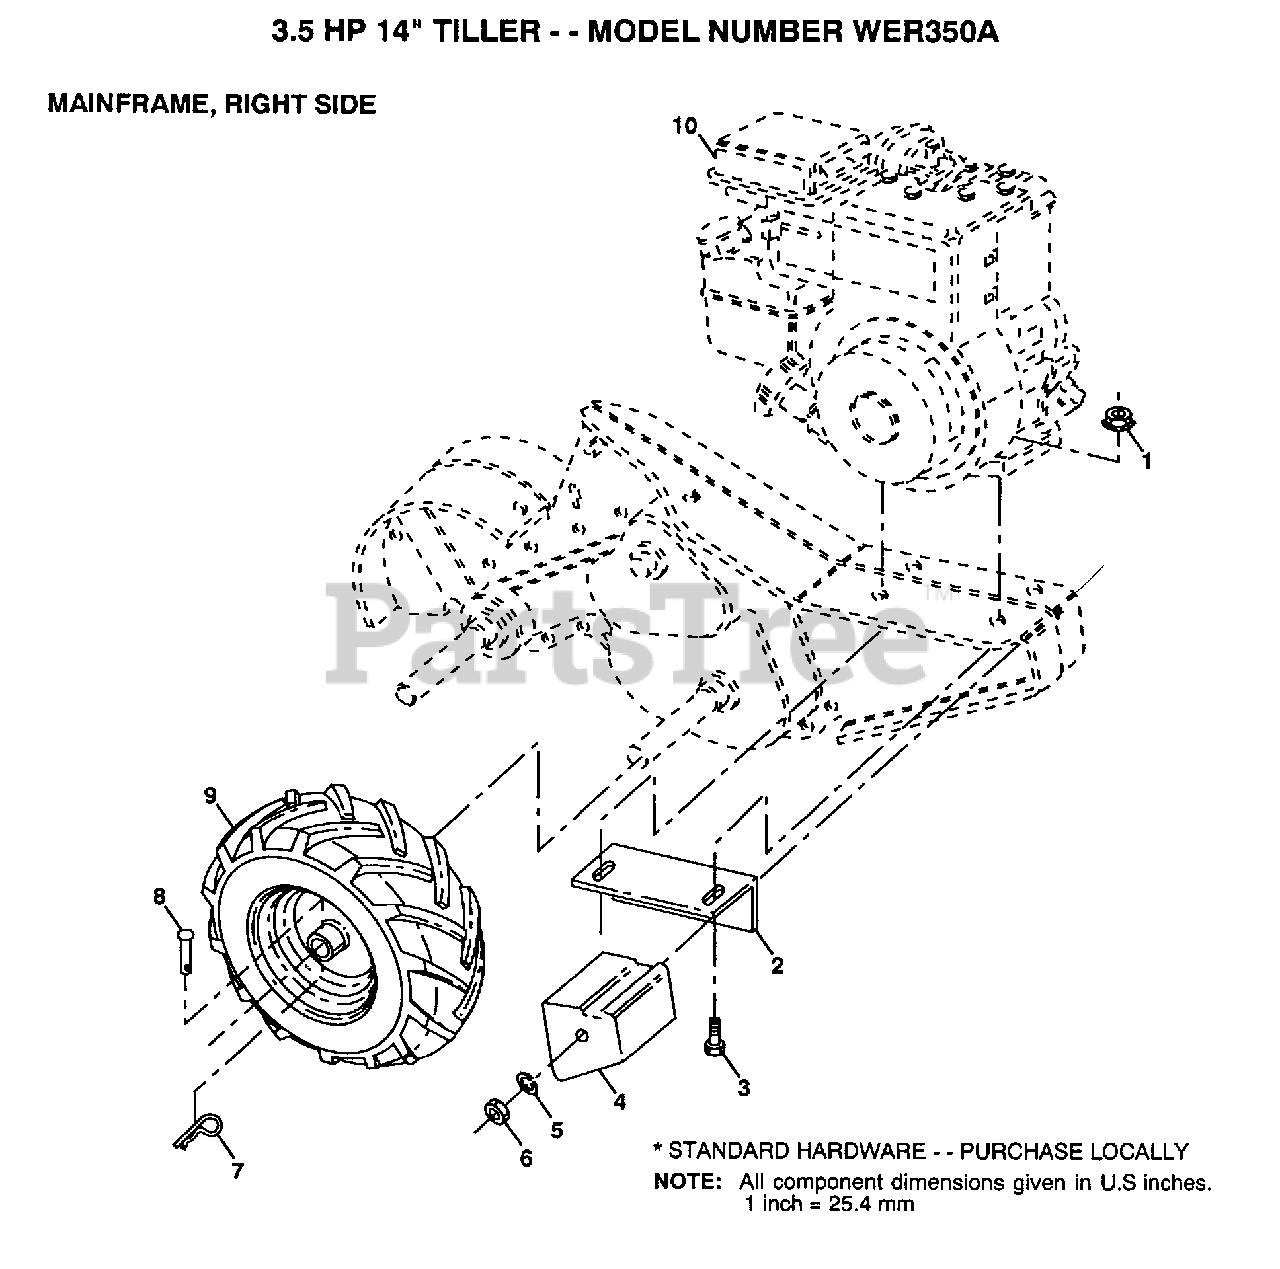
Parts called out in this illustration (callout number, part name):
2	BRACKET RH CRT
3	BOLT.HEX.5/16-1.5
4	COUNTERWEIGHT CRT
5	LOCKWASHER
6	NUT.HEX.3/8-16UNC
7	RETAINER M
8	RIVET.DRILL.1.75
9	TIRE.CHV.13X5.0-6
